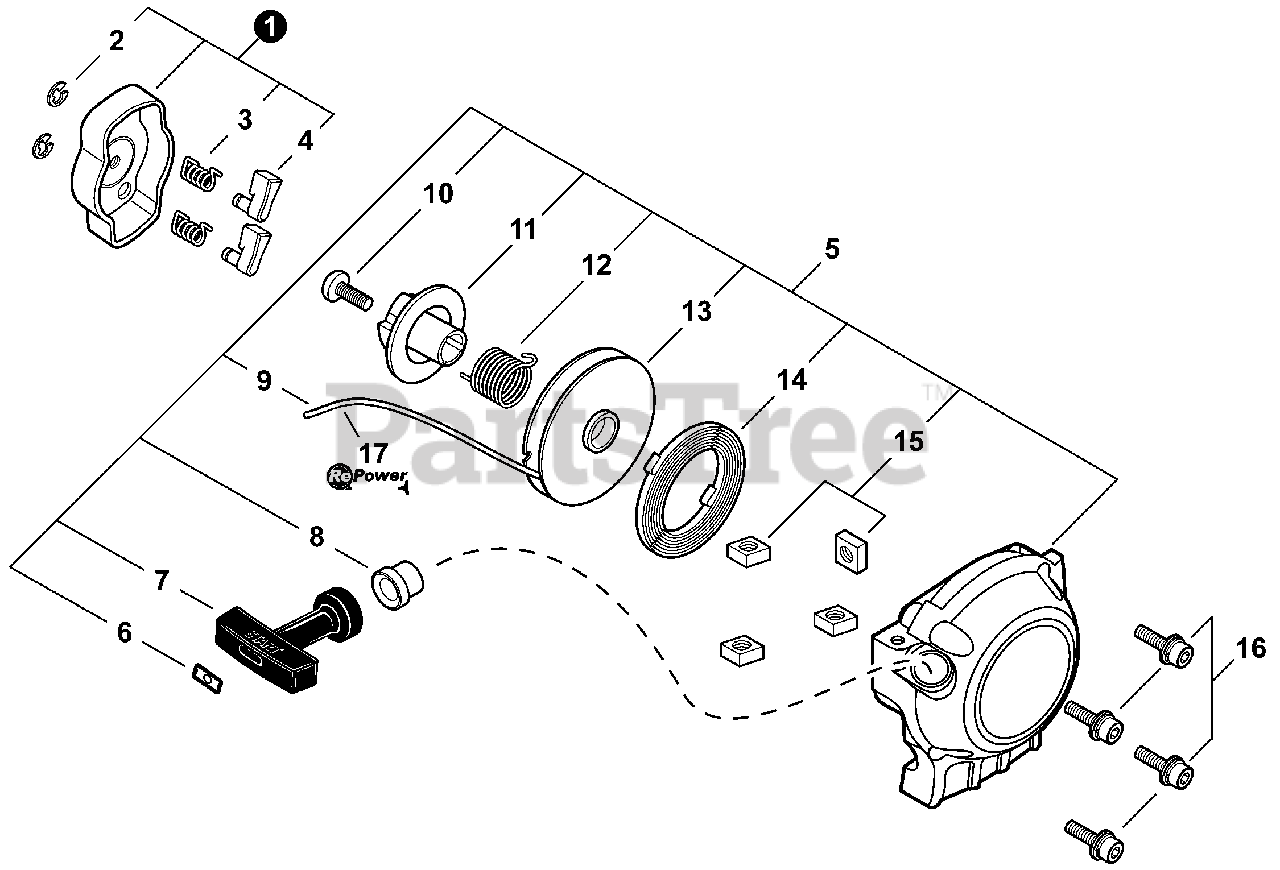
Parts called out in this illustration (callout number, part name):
1	PAWL ASSY, STARTER
2	E-RING 4
3	SPRING, RETURN
4	PAWL, STARTER
5	STARTER ASSY, RECOIL
6	RETAINER, ROPE
7	GRIP, STARTER
8	GUIDE, ROPE
9	ROPE, STARTER 3×700
10	SCREW
11	PLATE, CAM
12	SPRING, TORSION
13	REEL, ROPE
14	SPRING, RECOIL
15	NUT
16	BOLT 4×16
17	BULK STARTER ROPE - Ø 3.0 MM×61 M
